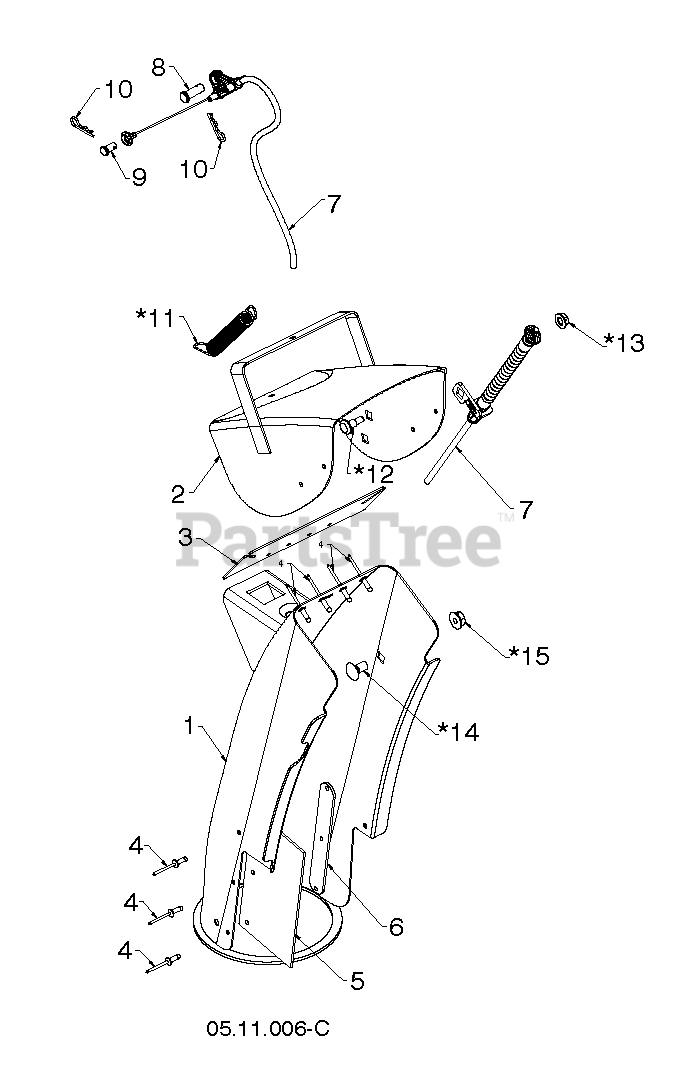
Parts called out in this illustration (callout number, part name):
1	RP_CHUTE.WELDMENT.SNOW.ORANGE
2	DEFLECTOR.WELDMENT.PNT.ORANGE
3	SEAL.DEFLECTOR
4	RIVET BLIND
5	SHIELD.SNOW.CHUTE
6	STRAP.SHEILD.RETAINER
7	CABLE CONTROL.CHUTE.DEFL.BOWDE
8	PIN CLEVIS 5/16X.875
9	PIN CLEVIS .25 X .31
10	HAIRPIN.SOFT.ZINC.059X1.125
11	SPRING.DEFLECTOR.REM.CHUTE
12	BOLT SHOULDER 1/4
13	NUT.HEX.LRG.FLANGE.1/4-20.LOCK
14	BOLT CAR BLK 5/16-18 X 5/8
15	LOCKNUT-FLANGE 5/16-18
